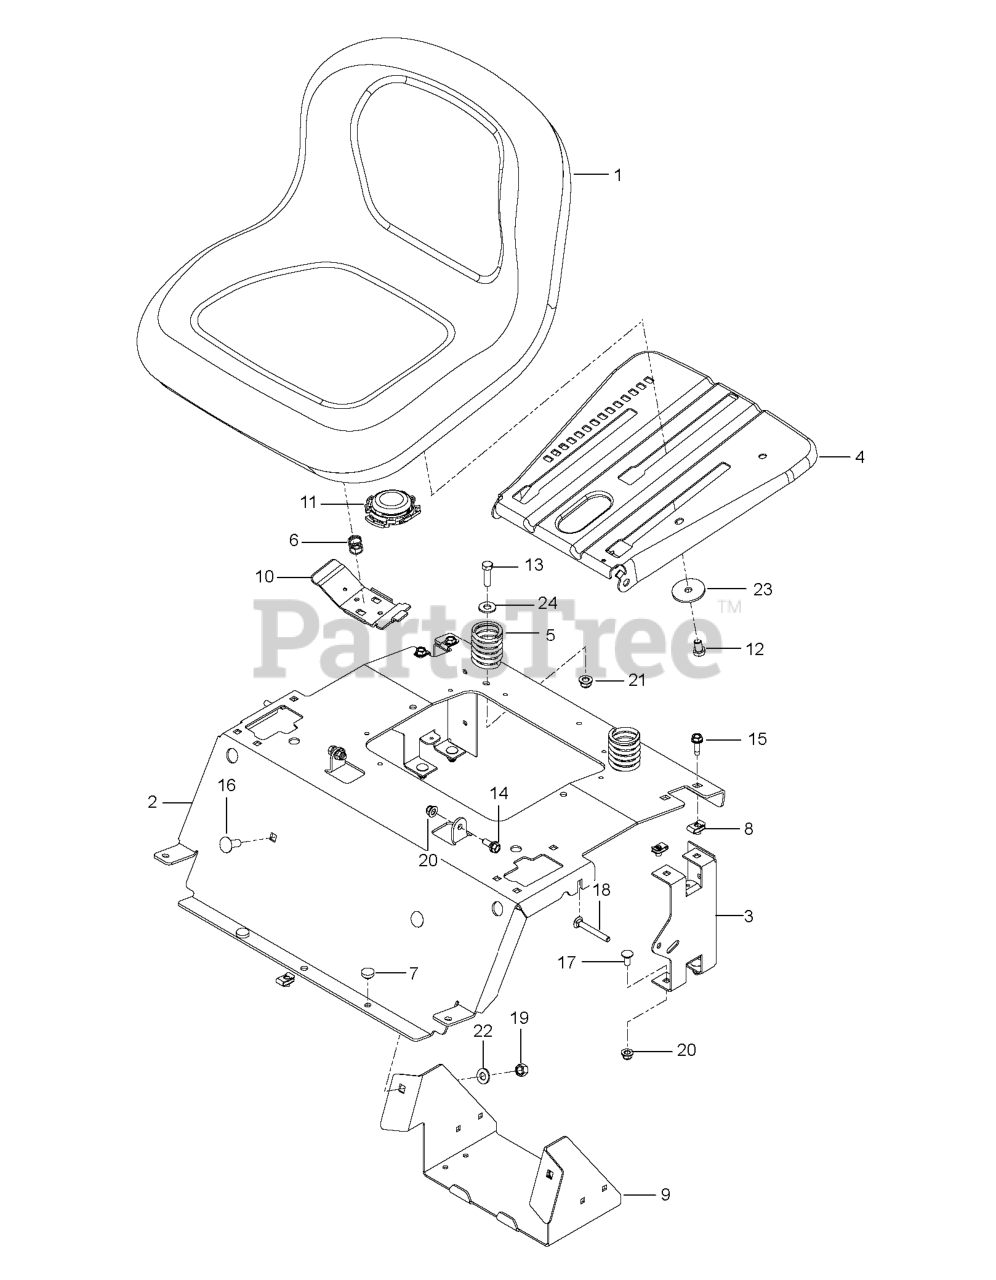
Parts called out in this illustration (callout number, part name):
1	RP SEAT, TH150, GREY, MILSCO
2	SUPPORT, SEAT ORANGE
3	SUPPORT, REAR SEAT, BLACK
4	PAN.ASM.SEAT.3PT
5	SPRING, SEAT
6	SPRING.LATCH.SEAT.TEX
7	GROMMET, BUMPER
8	U-CLIP 5/16-18 NUT RETAINER
9	BOX, BATTERY, BLACK
10	HANDLE.SLIDE.SEAT.TEX.BLACK
11	SWITCH, SEAT N/C
12	HCS 3/8-16 X 5/8 GR 5 ZD
13	HCS 3/8C X 1 1/4 GR5
14	BOLT, SHOULDER
15	BOLT 5/16-18 X 3/4
16	RHSNB 3/8C X 1
17	BOLT 5/16C X 3/4" CARRIAGE
18	RHSNB 5/16-18 X 2-1/2 GR5 ZD
19	NUT 3/8-16 NYLOC
20	5/16-18 NYLOC FLANGE NUT
21	NUT 3/8-16 HEX FLG NYLOC ZD
22	WASHER 3/8 SAE FLAT
23	WASHER, 3/8 SPEC
24	WASHER 3/8 FLAT
